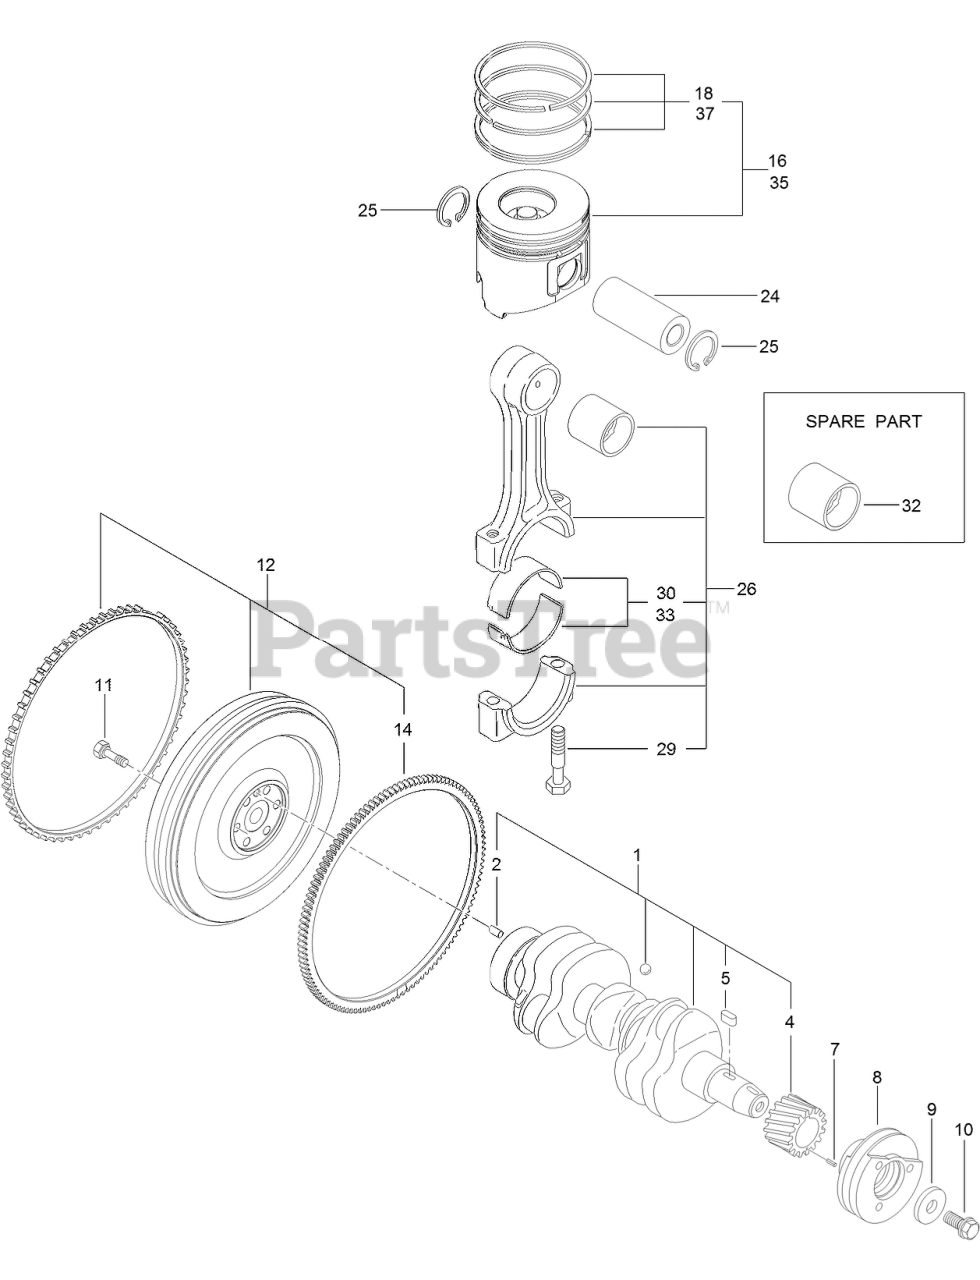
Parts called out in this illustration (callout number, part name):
1	CRANKSHAFT ASM
7	PIN-SPRING
8	PULLEY-V
12	FLYWHEEL ASM
16	PISTON ASM
18	PISTON RING ASM
26	CONNECTING ROD ASM
30	PIN-CRANK
32	PIN-PISTON
33	PIN-CRANK (.25)
35	PISTON ASM (0.25 O S)
37	RING SET (0.25 O S)
